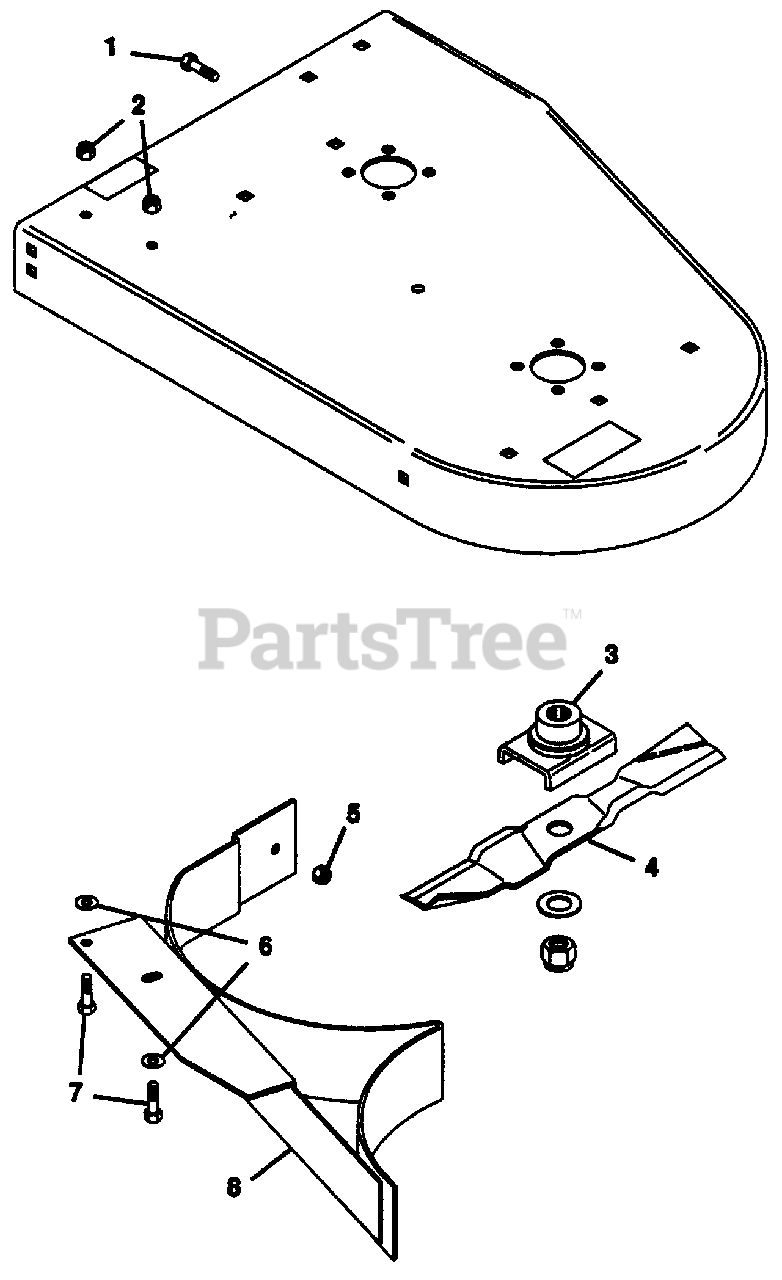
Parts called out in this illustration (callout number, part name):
1	Bolt, Hex 5/16-18x.750
2	Nut, Lock 3/8-16
3	Weldment, Blade Cradle
4	Blade, Mulching 36" Mower
5	Nut, Lock 5/16-18
6	Washer, Flat .406x.812x.065
7	Bolt, Hex 3/8-16x.75
8	Weldment, Mulching Baffle
